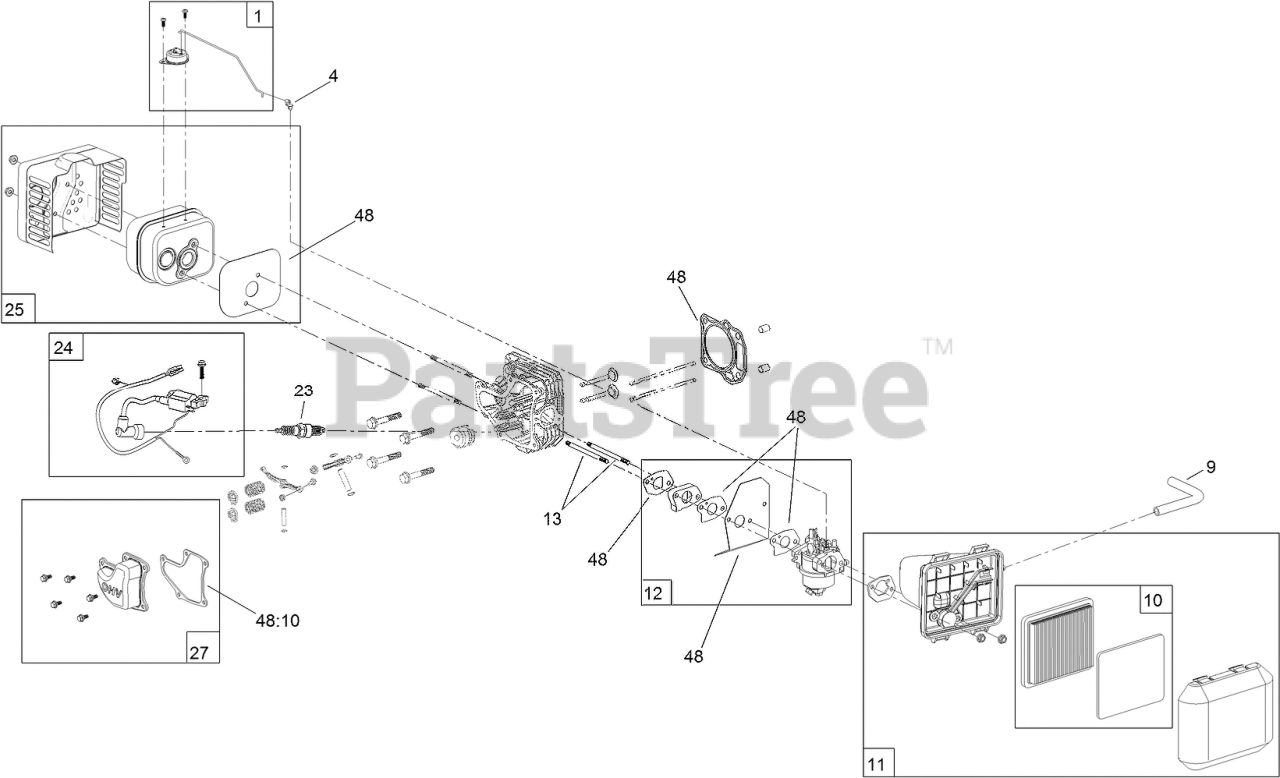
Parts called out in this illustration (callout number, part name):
1	THERMAL CONTROL KIT
4	LOCK-THROTTLE
9	TUBE-BREATHER
10	AIR FILTER AND PREFILTER KIT
11	AIR CLEANER ASM KIT
12	CARB REPLACEMENT KIT
12	CARB REPAIR KIT WITH GASKETS
13	STUD-INTAKE
23	SPARK PLUG
24	IGNITION COIL KIT, BBC
25	MUFFLER AND SHIELD KIT
27	VALVE COVER KIT
48	SEAL AND GASKET KIT
48:10	GASKET-VALVE COVER
